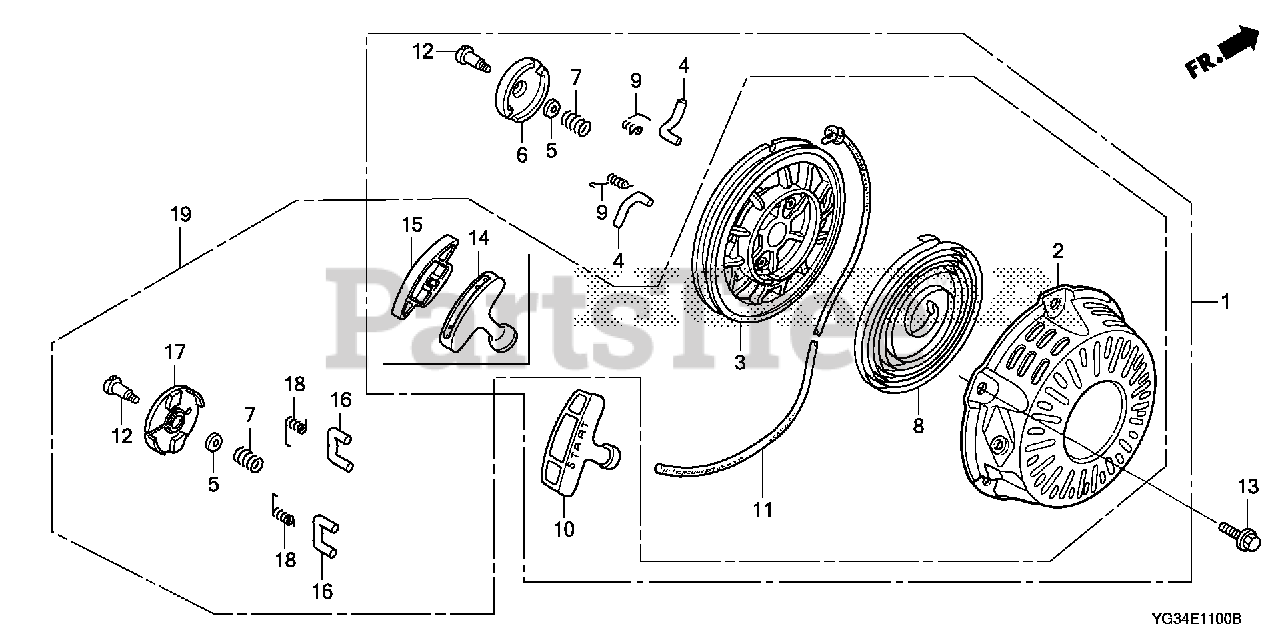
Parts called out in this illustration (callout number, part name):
2	CASE, RECOIL STARTER *R280* (POWER RED)
3	REEL, RECOIL STARTER (BLACK)
5	PLATE, FRICTION
7	SPRING, FRICTION
8	SPRING, RECOIL STARTER
11	ROPE, RECOIL STARTER (#5X55")
12	SCREW, SETTING
13	BOLT, FLANGE (6X8)
14	KNOB, RECOIL STARTER
15	KNOB, REINFORCEMENT
16	RATCHET, STARTER
17	GUIDE, RATCHET
18	SPRING, RETURN
19	STARTER ASSY., RECOIL *R280* (COO)(FOR U.S.A.) (POWER RED)
